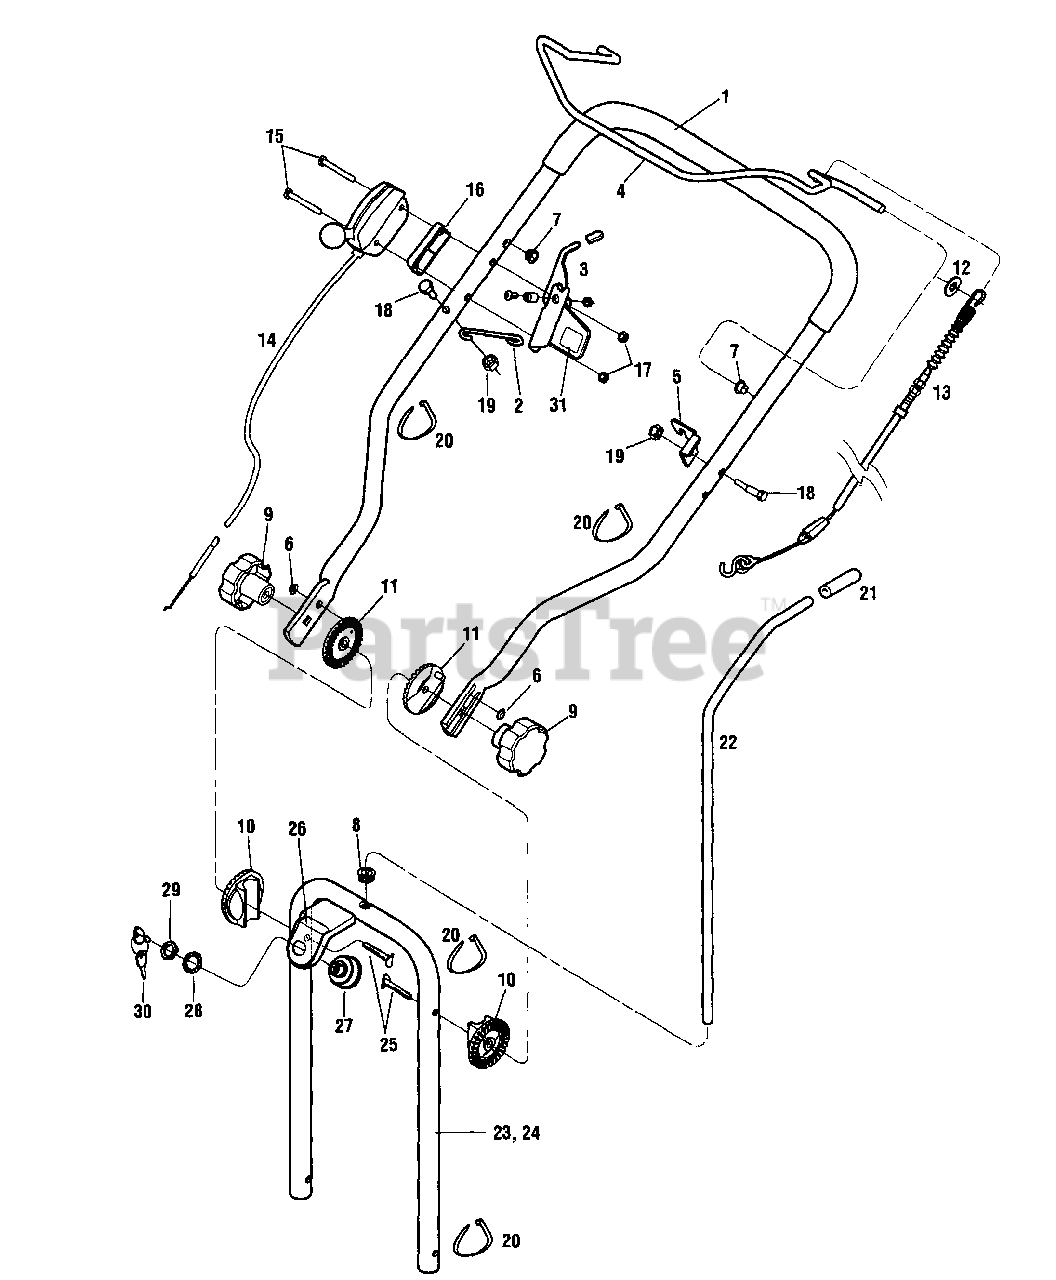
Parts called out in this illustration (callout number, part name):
1	Upper Handlebar w/sleeve
2	Rope Guide
3	Bail Stop/Latch Assembly
5	Cable Bracket
6	Push-on Retainer
7	Nyliner Bushing
8	Nyliner Bushing
9	Adjusting Knob
10	Inside Hndlbr. Adj. Quadrant
11	Outside Hndlbr. Adj. Quadrant
12	Flat Washer, 5/16
13	Control Cable
14	Throttle Cable
15	Screw, 10-24 x 2
17	Lock Nut, 10-24
18	Hex Hd Screw, 1/4-20 x 1-1/8
19	Top Lock Nut, 1/4-20
20	Cable Tie
21	Steering Rod Grip
22	Upper Steering Rod
23	Lower Handlebar.
24	Lower Handlebar.
25	Curved Hd. Bolt, 5/16-18 x 2
26	Decal-Keyswitch
27	Ignition Switch
28	Lockwasher, 5/8
29	Hex Nut, 5/8-32
30	Ignition Key
31	Bail Latch Decal
